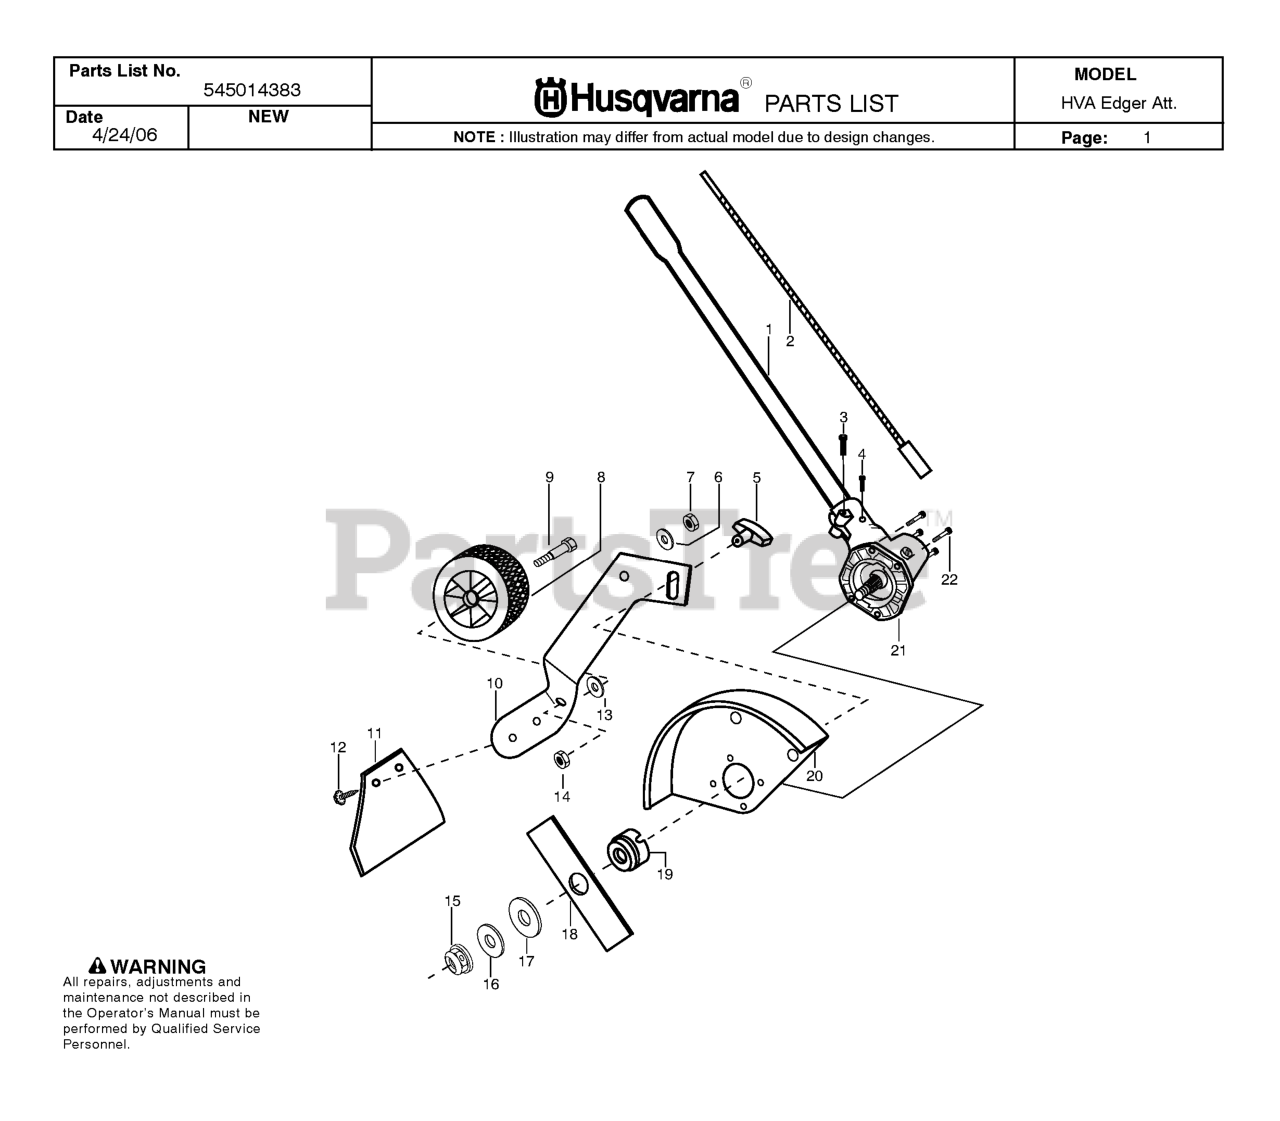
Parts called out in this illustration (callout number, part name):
2	FLEX-LOWER
3	SCREW - CARB. ADAPTOR
4	SCREW 8-16 X 9/16 (PLAS
8	WHEEL-4"(FRONT)(RUBBER)
9	BOLT-SHOULDER AXLE
10	WHEEL BRKT ADJ
11	KIT MUD FLAP
12	FASTENER MUD FLAP
15	NUT-FLANGE (LH)
16	WASHER BELLVILLE
17	WASHER-FLAT.
20	KIT - EDGER GUARD
21	KIT GEARBOX EDGER HUSQ
22	SCR 10-24 MS LDK PAN PH
530031159	HEX WRENCH 5/32
530150031	HANGER,ATTACHMENT
545074501	DECAL WARNING GUARD
